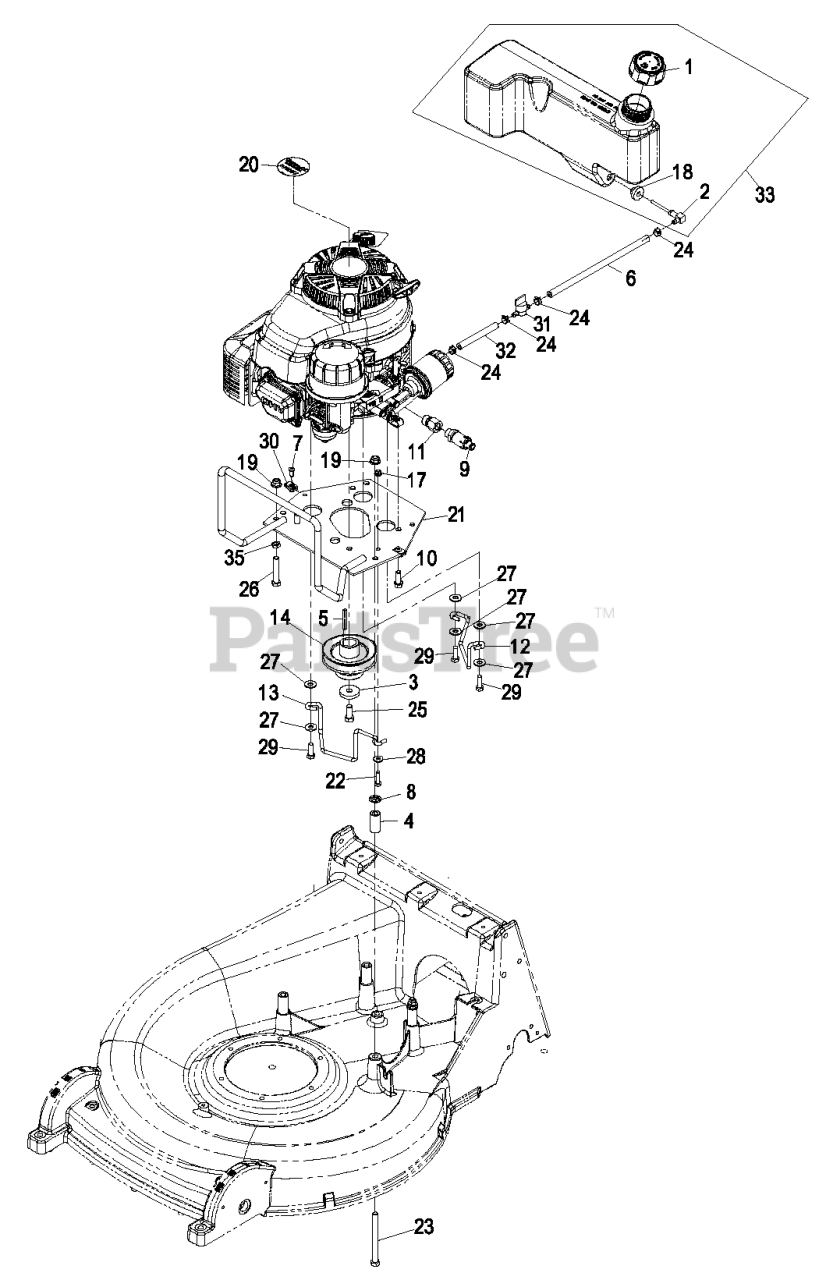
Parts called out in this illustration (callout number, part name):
1	CAP-FUEL
2	ELBOW-TANK, FUEL
3	WASHER-CLUTCH
5	KEY-SQUARE
6	HOSE-FUEL
8	RING-RETAINING
9	VALVE-DRAIN, OIL
10	SCREW-TAPTITE
11	ADAPTER
12	GUIDE-BELT, REAR
13	GUIDE-BELT, FRONT
14	SHEAVE-DRIVE
18	BUSHING
19	NUT-HF, NI
21	PLATE-ENGINE
22	SCREW-HH
23	SCREW-HH
24	CLAMP-HOSE
25	SCREW-HH
26	BOLT-CARR
27	WASHER-FLAT
28	WASHER-BELLEVILLE
29	SCREW-HH
30	Nut, Retainer-Panel 1/4-20
31	VALVE-FUEL
32	HOSE-FUEL
33	ASM,FUEL TANK M26 W/CAP
35	NUT-JAM
